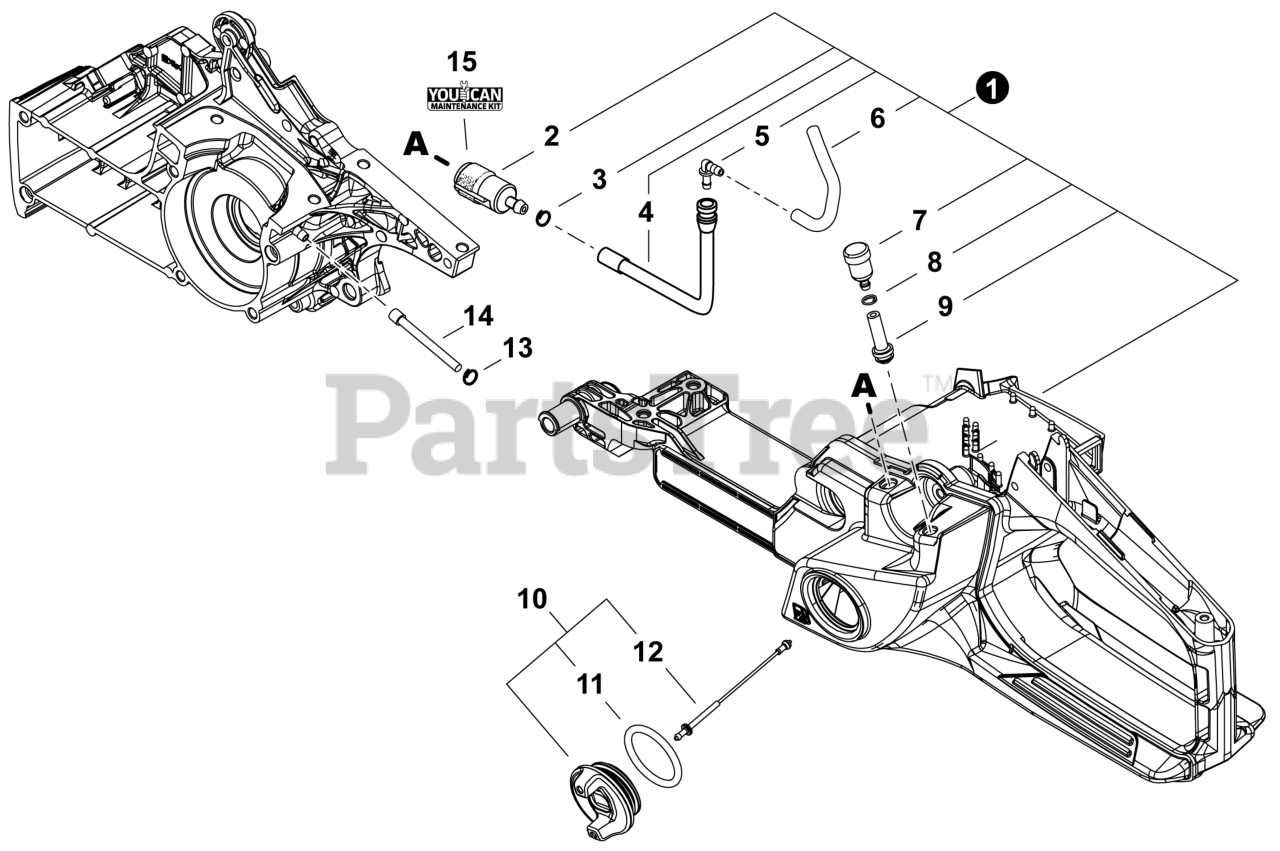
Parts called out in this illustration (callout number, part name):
1	HANDLE ASSY - REAR
2	FILTER, FUEL
4	PIPE, FUEL
5	CONNECTOR, PIPE
6	PIPE, FUEL 3.5x6x75 BLACK
7	VENT ASSY
8	CLIP 6.5 MM
9	PIPE, FUEL VENT
10	CAP ASSY, FUEL
11	O-RING 29
12	CONNECTOR, CAP
14	PIPE, FUEL 3x6(8)x130 BLACK
15	TUNE-UP KIT - YOUCANT
